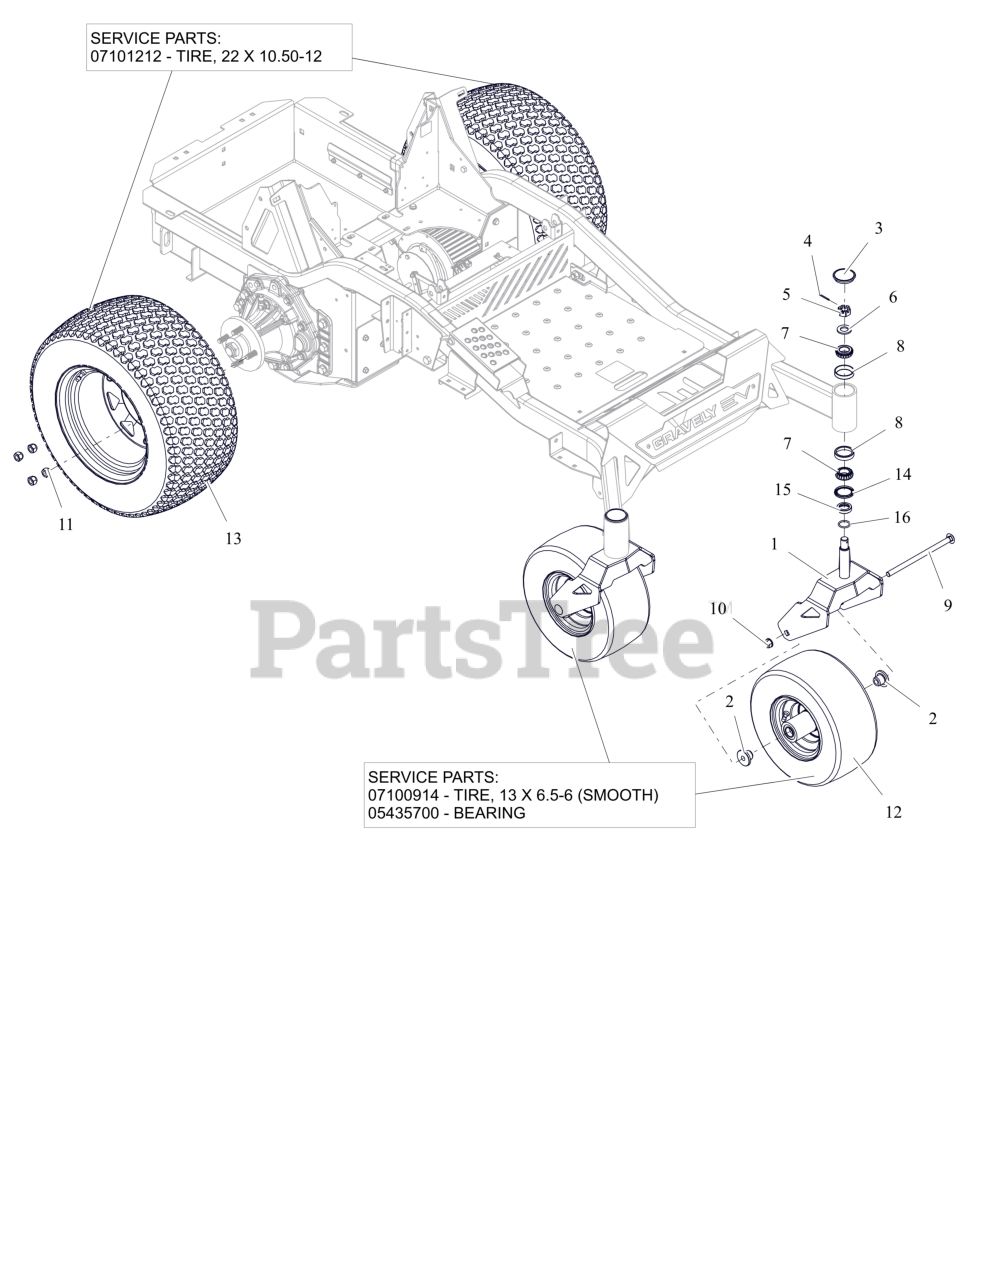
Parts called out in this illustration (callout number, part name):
1	WLDMT- CASTER FORK
2	SPACER, FRONT WHEEL
3	CAP, DUST
4	PIN,CTR.12X1.25EXTPRSQCT ZC120
5	NUT, SLOTTED .75-16
6	WSHR-FL-STL 0.812X1.469X0.134 ZCC
7	BRG-CONE 1.0X.58
8	BRG-CUP1.980X.420
9	BTL,RHSN .500-13 X 9 G5 ZCC
10	NUT-LK-CTR-FLG .500-13 GG ZCC
11	NUT, WHEEL .50-20 ZCC
12	ASM, WHL/TIRE 13X6.50-6
12	TIRE, 13X6.50-6 SMOOTH
12	BRG, 25MM ID X 52MM OD X 15MM
12	TIRE TUBE 13X6.5-6
13	ASM, WHL/TIRE 22X10.50-12 K500
13	TIRE, 22X10.50-12
13	TUBE 22,23&24X8.50/9.50/10.00/10.50/12.00-12
14	BEARING SEAL 1.5 X 2 X .18
15	SPCR, CASTER FORK (1.00)
16	O-RING 1.000X1.250X
